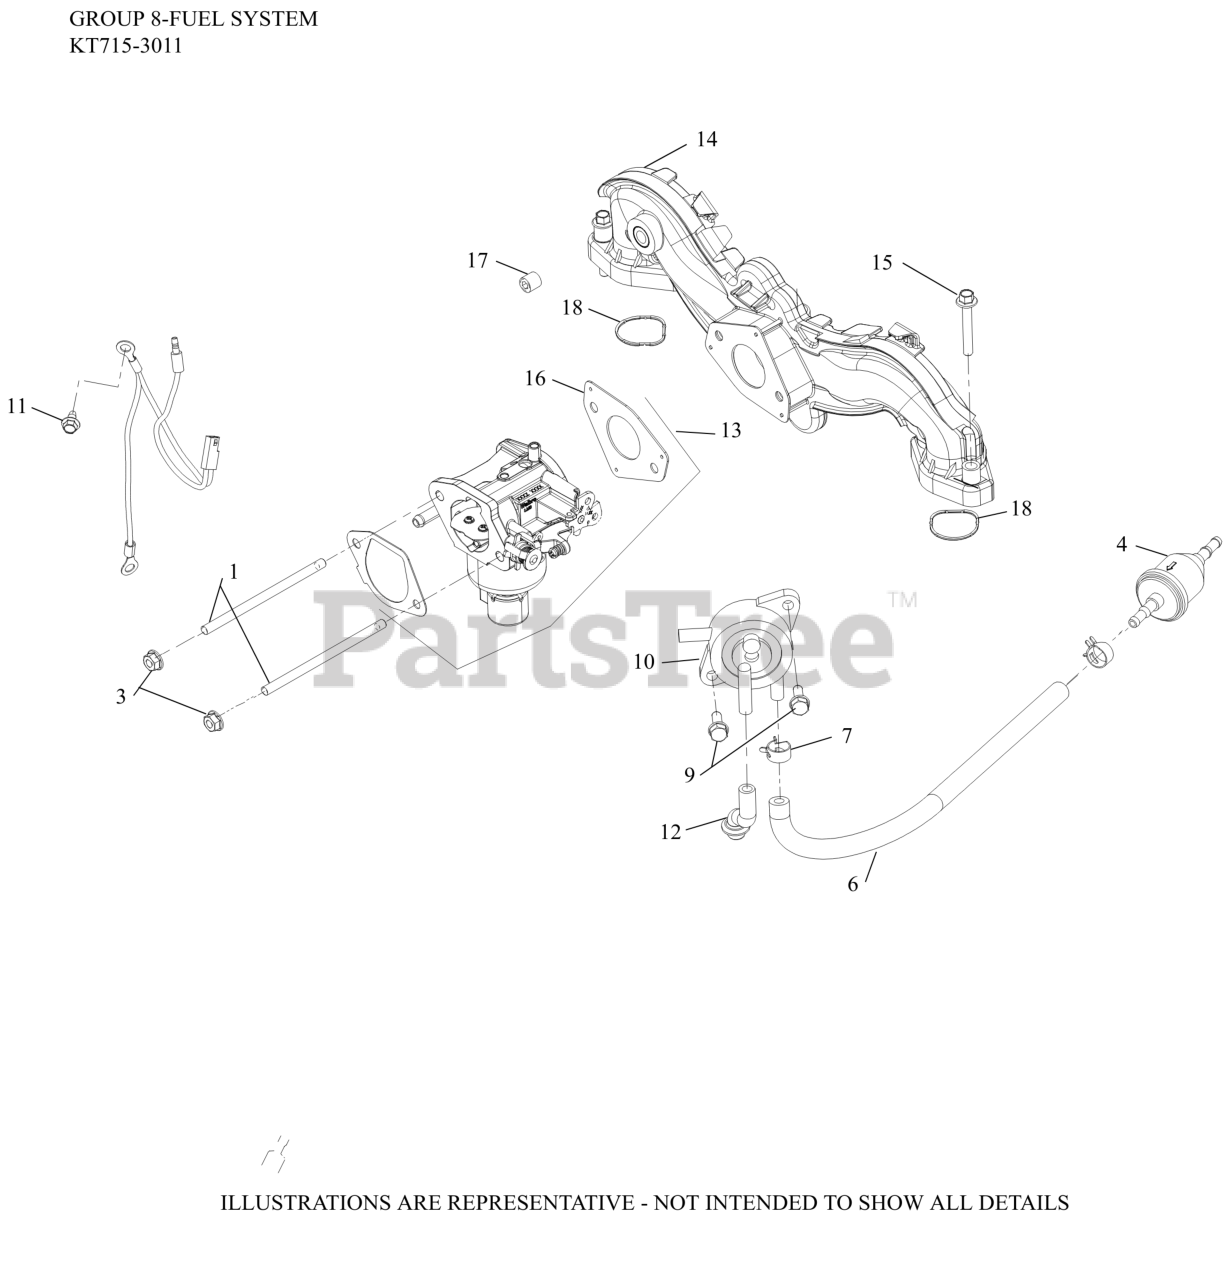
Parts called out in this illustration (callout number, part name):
3	NUT, FLG M6X1.0
4	FILTER,FUEL 51 MICRON (FUEL PUMP)
6	HOSE,LW PERM.FUEL 24.00"-USE 25 111 81-S
7	SPRING CLAMP, HOSE
9	SCREW, TAP M6X1.7X18
10	PUMP, FUEL (PULSE)-(#2539326S)
11	SCREW, THREAD FORMING
12	HOSE, PULSE PUMP(STEEL COVERS)
13	KIT,CARB(WALBRO)
14	KIT, INTAKE MANIFOLD-(#24164277S)
15	SCREW, FLG M6X1.0X40
16	GASKET, CARBURETOR
17	PLUG, CTSK PIPE 1/8"
18	O-RING, INTAKE PORT (PIM)
NI	KIT,REPAIR OVERHAUL(WALBRO)
NI	KIT,BOWL O-RING(WALBRO)
NI	KIT, HI ALTITUDE (5000 FT) 22MM
NI	KIT, SOLENOID REPAIR
NI	KIT, FLOAT REPAIR
NI	CLIP, CABLE (KM)
